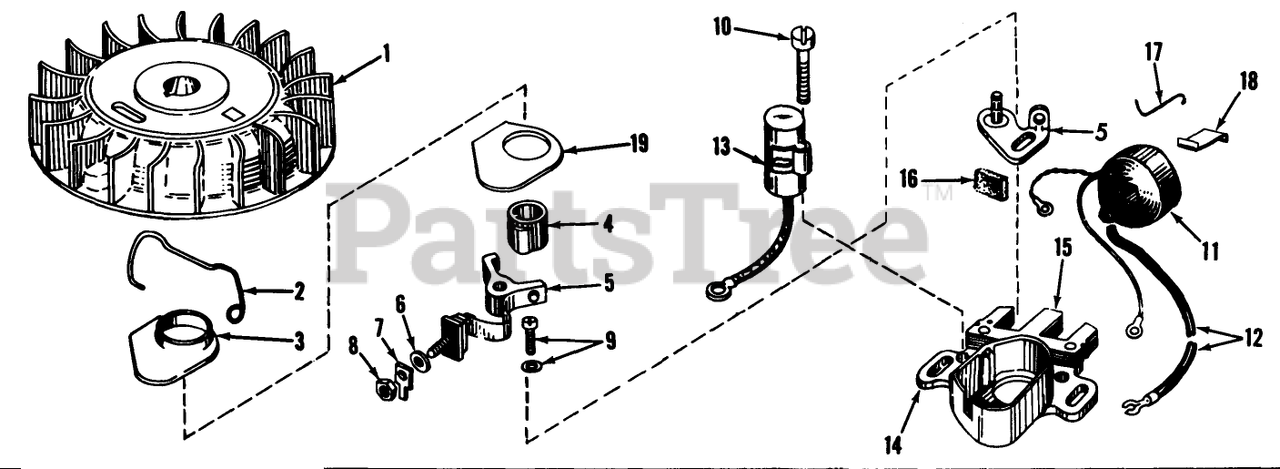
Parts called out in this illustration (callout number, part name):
1	Flywheel
2	Spring Breaker Box
3	Cover, Dust
4	Cam-Breaker
5	Breaker Assv.
6	Washer
7	Terminal
8	DECAL
9	Breaker Screw
10	Condenser Screw
11	Coil Assy., (Inc. Ref. Nos. 12, 13 18)
12	Wire, Lead
13	Condenser
14	Core Plate
15	A Stator Assy. (Incl. Nos. 5 thru 14, 16, 17 18)
16	Felt,Cam Wiper
17	Clip, Coil
18	Spring Coil Wedge
19	Gasket Dust
